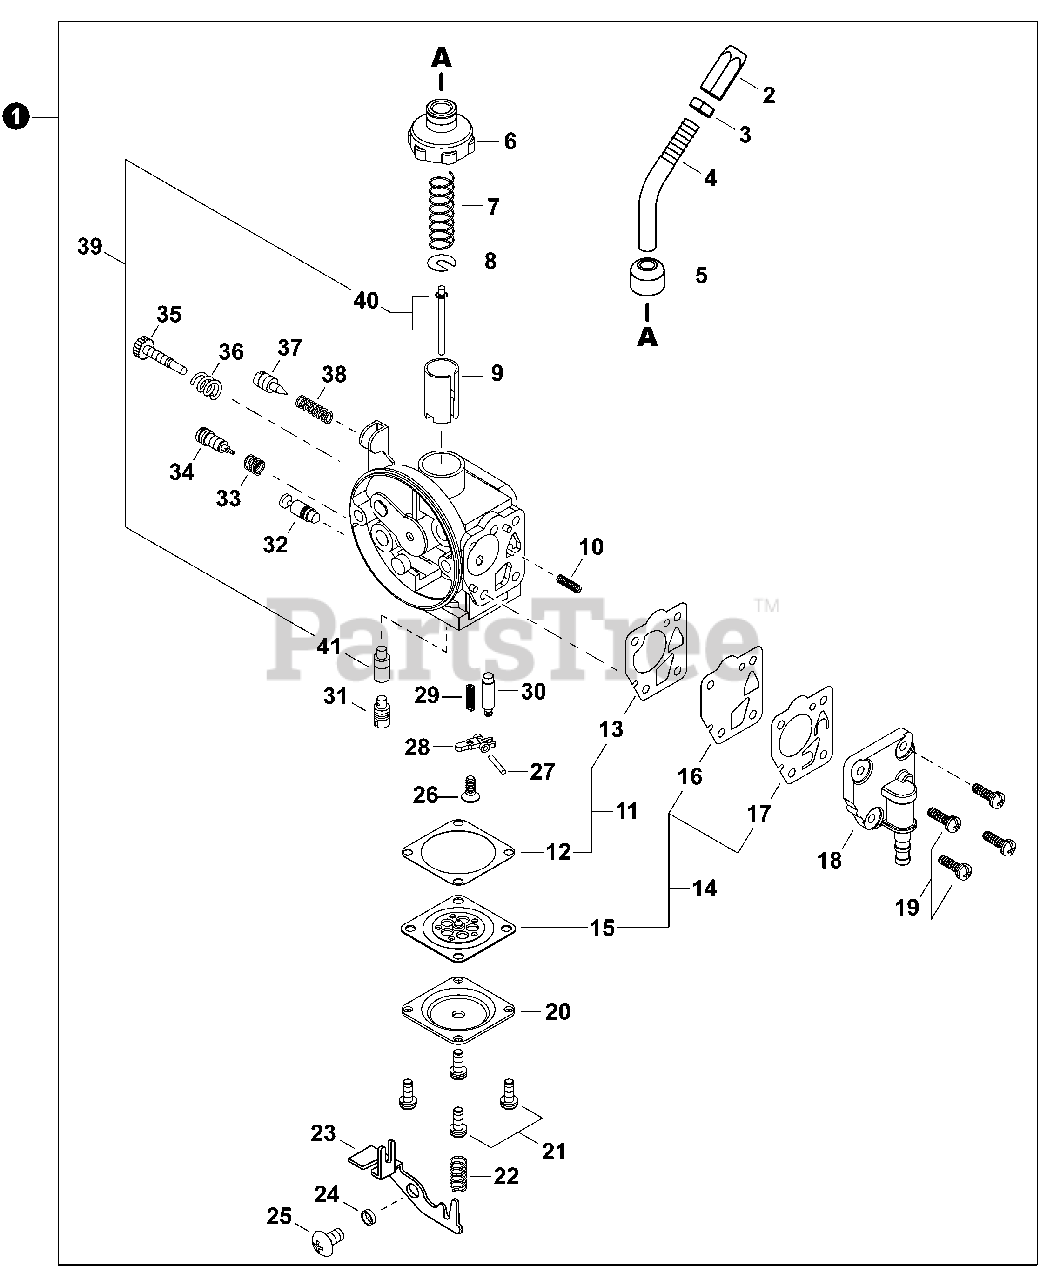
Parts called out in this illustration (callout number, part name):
1	CARBURETOR DPW12-1A
2	ADJUSTER, CABLE
3	NUT, LOCK
4	PIPE, CABLE ADJUSTER(4 pieces ×2 M)
5	CAP
6	CAP, CARBURETOR
7	SPRING, THROTTLE
8	WASHER
9	VALVE, THROTTLE
10	SPRING, COIL
11	GASKET KIT
12	GASKET
13	GASKET, DIAPHRAGM
14	DIAPHRAGM KIT
15	DIAPHRAGM, METERING
16	DIAPHRAGM, METERING
17	VALVE, PUMP
18	BODY, PURGE
19	SCREW
20	COVER, METERING DIAPHRAGM
21	SCREW M3×8
22	SPRING
23	LEVER, TICKLER
24	COLLAR
25	SCREW
26	SCREW, METERING LEVER PIN
27	PIN, METERING LEVER
28	LEVER, METERING
29	SPRING, VALVE
30	VALVE, INLET NEEDLE
31	HOLDER, MAIN JET
32	VALVE, OVERFLOW
33	SPRING
34	SCREW, MAIN ADJUST
35	SCREW, IDLE ADJUST
36	SPRING
37	SCREW, SLOW AIR
38	SPRING
39	NEEDLE / JET KIT
40	NEEDLE, JET
41	JET, MAIN
